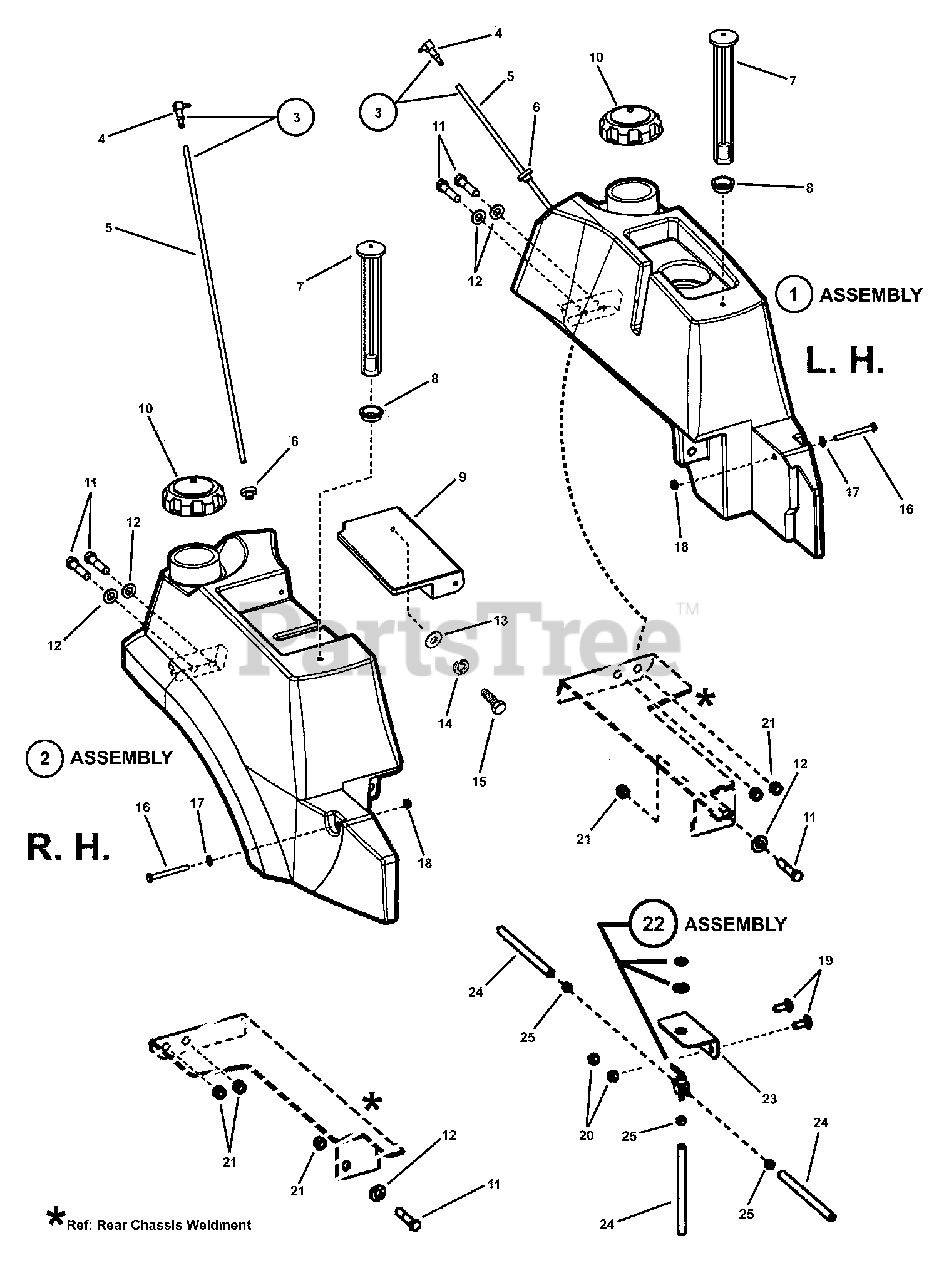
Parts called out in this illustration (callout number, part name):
1	ASSEMBLY, LH Fuel Tank
2	ASSEMBLY, RH Fuel Tank
3	ASSEMBLY, Fuel Pickup
4	ELBOW, 90 Degree
5	TUBE, Pickup
6	GROMMET, Tube
7	GAGE, Fuel
8	GROMMET, Gage
9	LID, Fuel Tank
10	CAP, 3-1/2" Fuel
11	SCREW, 7/16-14 x 2" Hex Head Cap, GR 5
12	WASHER, 1/2" Flat SAE
13	WASHER, 1/4" Flat
14	WASHER, 1/4" Split Lock
15	SCREW, 1/4-20 x 1-1/4" Hex Head Cap, GR 5
16	SCREW, 5/16-18 x 2-1/2" Hex Head Cap, GR 5
17	WASHER, 5/16" Flat
18	NUT, 5/16-18 HEX NYLON LOCK
19	BOLT, 3/8-16 x 1" Square Neck Carriage, GR 5
20	NUT, 3/8-16 HEX NYLON LOCK
21	NUT, 7/16-14 HEX NYLON LOCK
22	FUEL VALVE, 3-Way
23	BRACKET, Tank Selector
24	HOSE, 1/4" I.D. x 3'-7.5" Long Fuel
25	CLAMP, Fuel Hose
